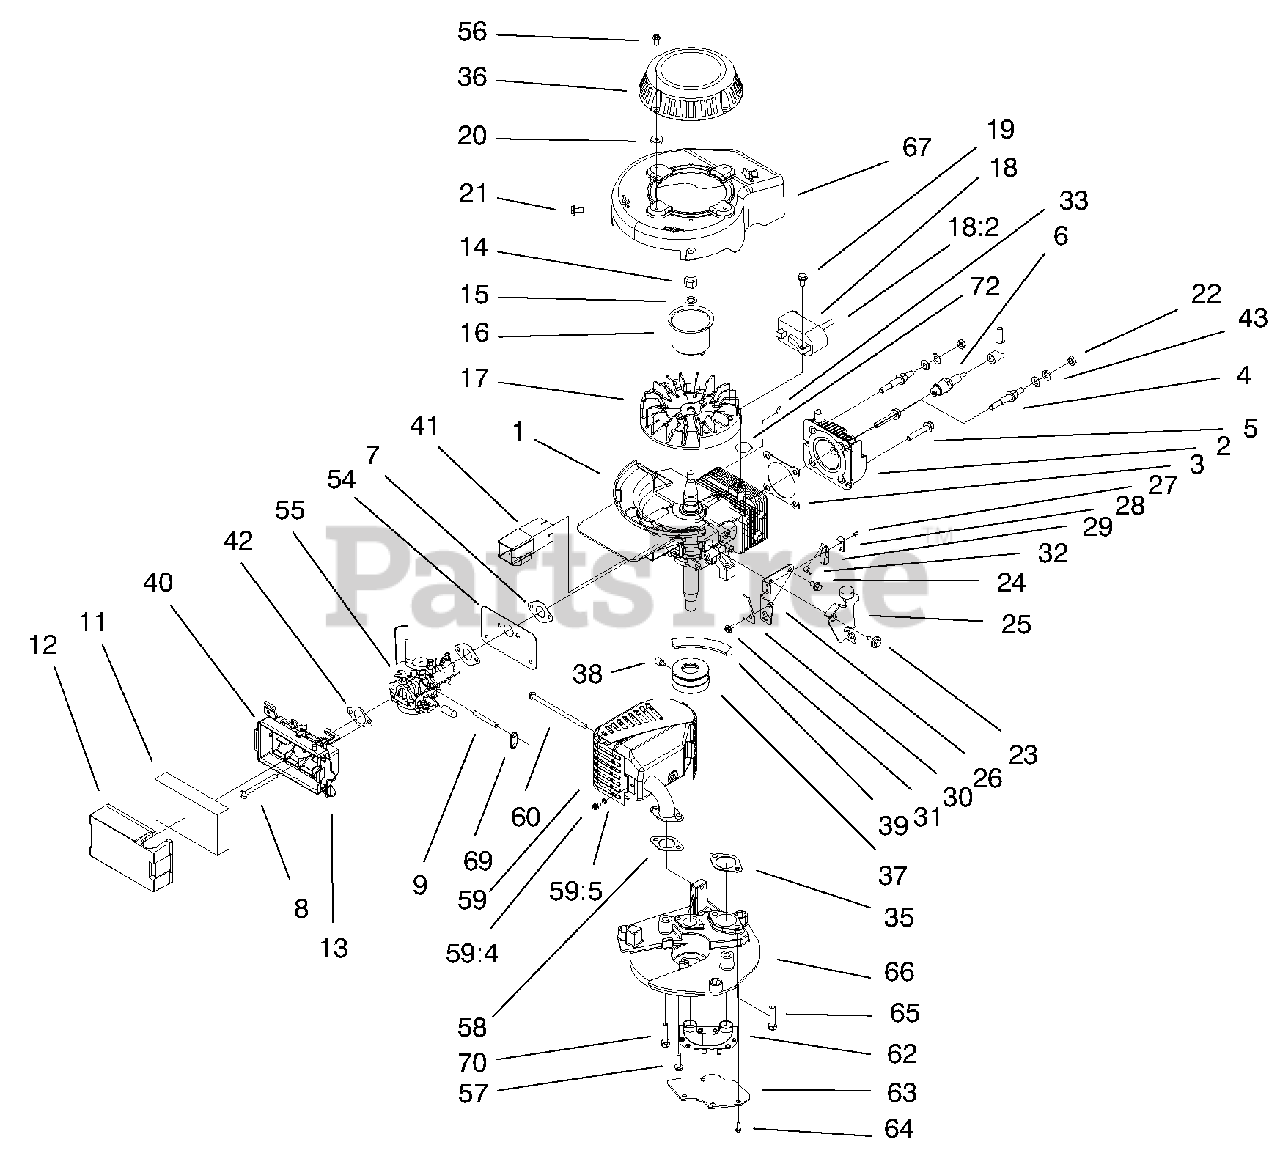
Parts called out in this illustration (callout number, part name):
1	E-S/Block Ser.
2	Head-(Mach)
3	Gasket-Head
5	Bolt-Head
6	Plug-Spark
7	Gasket-Intake
9	Primer Hose
11	Filter-Air
12	Cover-Air Filter
13	Retainer-Fil.
15	Washer-Lock
16	Hub Starter
17	Flywheel-Machined
18	Ignition-Cd
18:2	Ht Lead&cover
18:2	Cover & Term. Ay
19	Screw-Cd Mtg
21	Screw-HH
23	Screw-Shoulder
24	Screw-HWH
25	Brake Plate Ay
26	Plate-Brake Mtg
27	Rivet-Plastic
28	Strap-Insulation
29	Strap-Ground
30	Stop-Gr Strap
31	Screw-Special
32	Wire-Lead
35	Gasket-Exhaust
36	Starter Assy Sm
38	Screw-Set
40	Base Ay-(Air Filter)
42	Gasket-Filter
43	Washer-Belleville
54	Shield-Carb.
55	Carburetor ASM With Gaskets
56	Screw Sems
57	Screw-Cd Mtg
59	Muffler And Guard ASM
59:4	Screw-HWH
59:5	Washer-Lock/Int
60	Bolt-Console
62	Pipe-Transfer
63	Cover-Muffler
64	Screw-HH
65	Screw-HH
66	Mtg. Plate
67	Assembly-Shroud
69	Hose-Retainer
70	Screw H.hd.wash
72	Strap-Tie
